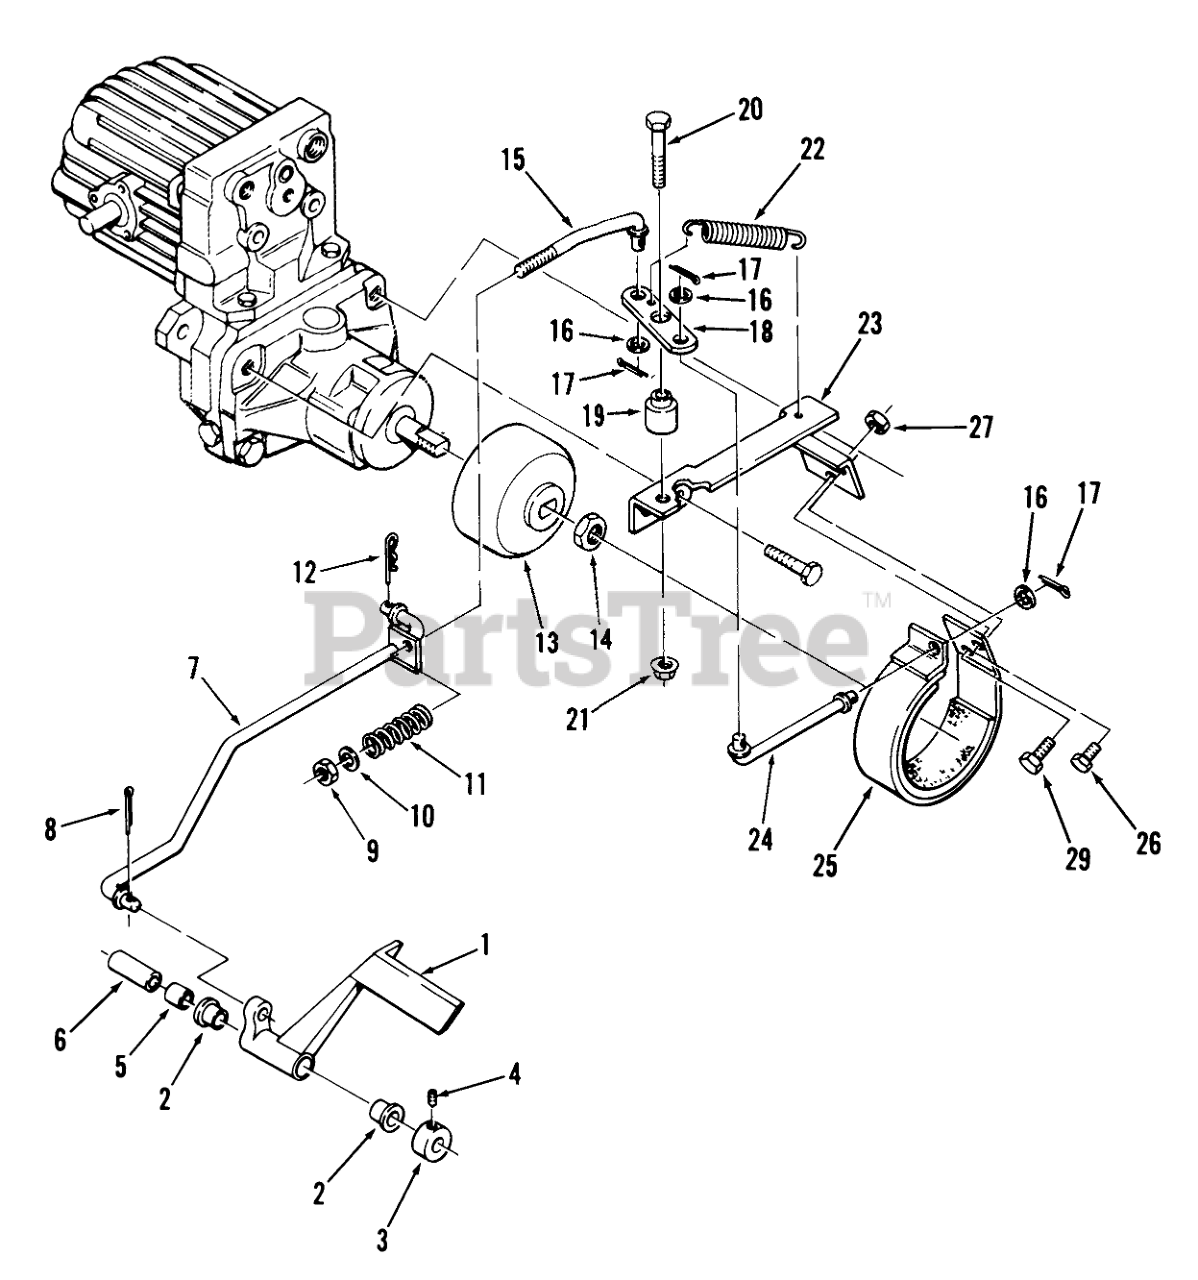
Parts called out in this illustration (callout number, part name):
1	PEDAL R
2	BUSHING
3	Collar
4	SCREW-SET
5	Spacer
6	SPACER
7	Brake Rod-Front
7	BRAKE ROD ASSY R
9	Nut
10	Washer
11	SPRING
13	ASSY-BRAKE DRUM
14	E.S. Nut 9/16-18 Thin
16	Washer
17	Pop Rivet
18	Lever
19	SPACER
20	BOLT
21	Nut
22	CLUTCH SPRING
23	Brake Bracket
25	BRAKE BAND ASM
26	H H C S
27	Nut
29	Bolt
